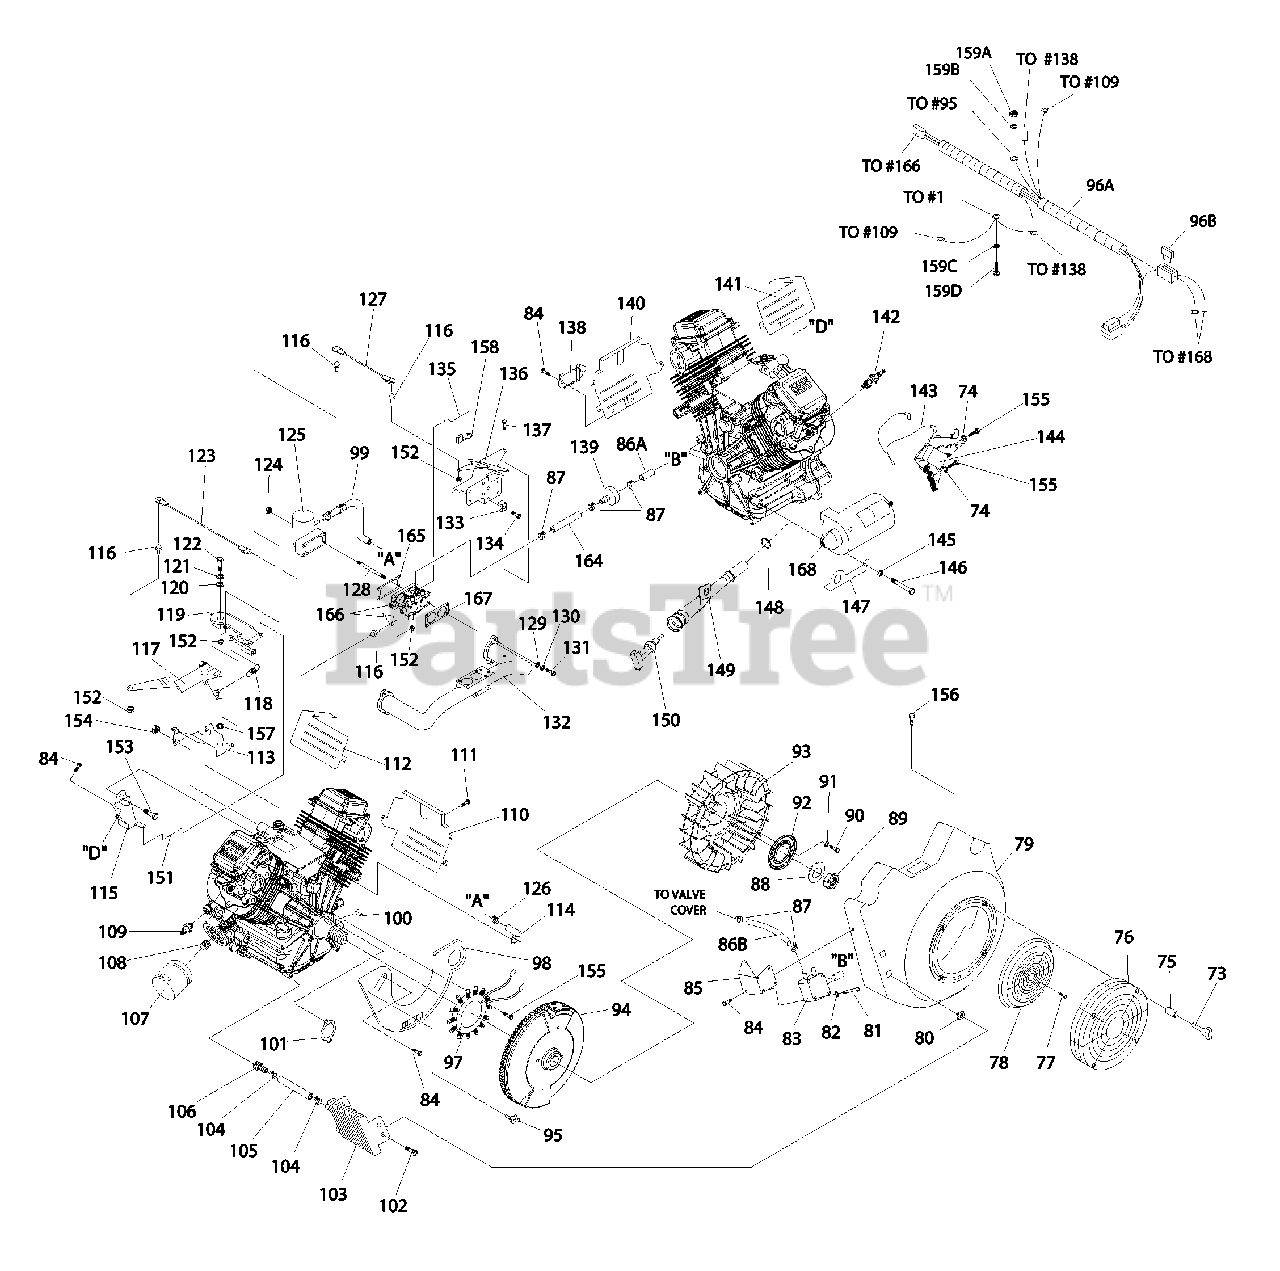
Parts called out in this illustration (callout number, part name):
73	KNOB AIR CLEANER
74	WASHER, LOCK M6-1/4"
75	SPACER, ROTATING SCREEN GUARD
76	GUARD, ROTATING SCREEN
77	SCREW, #10 SHEET METAL
78	SCREEN, ROTATING
79	HOUSING, BLOWER VERTICAL
80	NUT, GROMMET 1/4 PLUG
81	SCREW PPHM M4-0.7 X 40
82	WASHER, LOCK M4
83	PUMP, IMPULSE
84	SCREW TAPTITE M6-1.0X 10 YELLOW CHROME
85	BRACKET, FUEL PUMP
86A	HOSE ¼" ID X 2" LONG
86B	HOSE ¼" ID X 7" LONG
87	CLAMP HOSE BAND 1/4
88	WASHER, M24
89	NUT,HEX M24
90	SCREW HHC M8-1.25 X 10 G8.8
91	WASHER SHAKEPROOF INT M8 SS
92	PLATE, FAN
93	FAN, NYLON
94	FLYWHEEL ASSEMBLY
95	INSULATOR ASSEMBLY IGNITION
96A	VS WIRE HARNESS
96B	30 AMP FUSE
97	ASSEMBLY, STATOR W/ LUGS
98	PLATE, BACKING WITH OIL COOL
99	ASSY,BREATHER TUBE
100	KEY, WOODRUFF 4 X 19D
101	GASKET, MANIFOLD / PORT
102	PLASTITE,1/4-15 X 3/4
103	COOLER, OIL
104	CLAMP HOSE .38 - .87
105	HOSE, 3/8" I.D. X 6" LONG
106	BARBED STR 1/4NPT X 3/8 WITH VIBRA SEAL
107	FILTER, OIL D 69 X 64 LONG
108	NIPPLE, 3/4"-16 UNF
109	SWITCH, OIL PRESS
110	WRAPPER, LOWER CYLINDER 1
111	SCREW THTT #10-24 X 3/8"
112	WRAPPER, UPPER CYLINDER 1
113	BRACKET, SUPPORT-GOVERNOR ADJUST
114	HOSE, BLOWER HSG TO BREATHER
115	ASSY, IDLE SPEED SUPPORT BRACKET
116	STUD, BALL M3-0.5
117	ASSY, GOVERNOR LEVER
118	SPRING, GOVERNOR
119	ASSY, IDLE SPEED ADJUST W/ GROMMET
120	WASHER, FLAT M5
121	WASHER, LOCK M5
122	SCREW, HHC M5-0.8 X 10
123	ROD, GOVERNOR
124	NUT LOCK FLANGE M6-1.0
125	ADAPTOR,CARB-AIRBOX,M6 BOSSES
126	HOSE CLAMP, BAND 12mm I.D.
127	ASSEMBLY, IDLE SPEED ADJUSTMENT ROD
128	STUD, METRIC
129	WASHER, FLAT M8
130	WASHER, LOCK M8
131	SCREW, SHC M8-1.25 X 30
132	MANIFOLD,INTAKE 2BBL CARB
133	CLAMP, 3/16" COATED CABLE
134	SCREW, PPHM M5-0.8 X 12
135	ROD, CHOKE
136	ASSY, BELDEN BRACKET W/ BELLCRANK
137	SCREW HHFC M6-1.0 X 8mm
138	REGULATOR, 20 AMP
139	FILTER, FUEL
140	WRAPPER, LOWER CYLINDER 2
141	WRAPPER, UPPER CYLINDER 2
142	SPARK PLUG RC12YC
143	ASSEMBLY, GROUND WIRE
144	ASSEMBLY, IGNITION COIL
145	WASHER, LOCK M8-5/16
146	SCREW, HHC M8-1.25 X 85 G8.8
147	LIFT HOOK, STARTER
148	O-RING, OIL CLR
149	TUBE, DIPSTICK
150	ASSEMBLY, DIPSTICK W/ HANDLE
151	ROD, IDLE ADJUSTMENT
152	NUT, LOCK HEX M3-0.5
153	SCREW, SHC M10-1.5 X 75 G10.9
154	NUT, LOCK FL-SERRATED M10-1.5
155	SCREW, TAPTITE M6-1.0 X 25
156	SCREW, FHHC M6-1.0 X 12 W/M5 HEX
157	WASHER NYLON 0.375" I.D.
158	BUSHING, GOVERNOR ROD
159A	NUT HEX #8-32
159B	WASHER LOCK #8-M4
159C	WASHER LOCK M3
159D	SCREW PPHM M3-0.5 X 8
164	HOSE ¼" ID X 8.5" LONG
165	GASKET, CARB TO SPACER
166	CARBURETOR
167	GASKET, MANIFOLD TO CARB
168	STARTER, V-TWIN ENGINE
